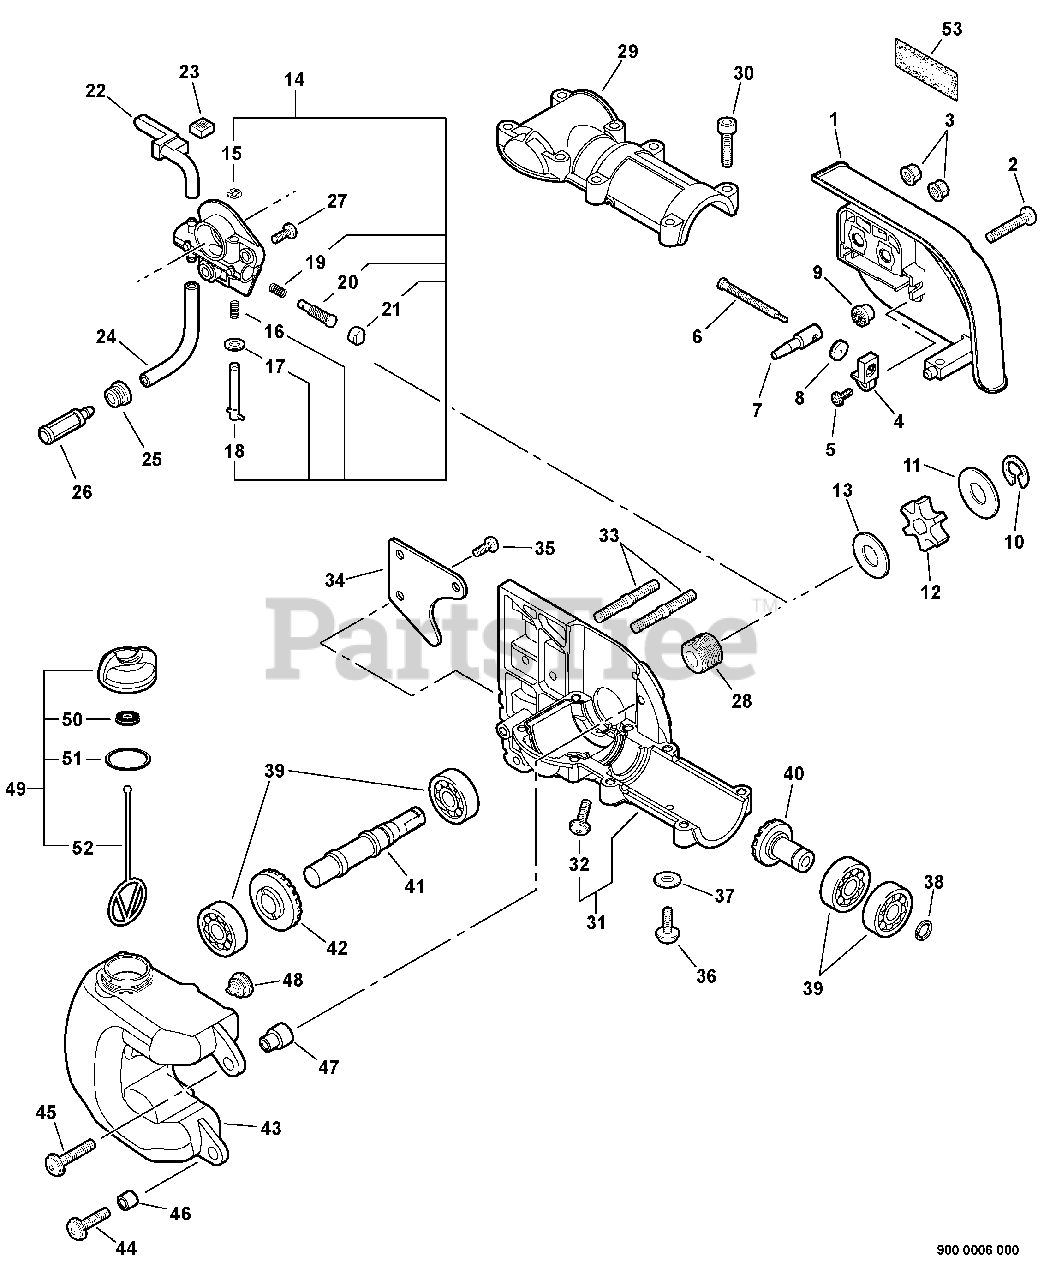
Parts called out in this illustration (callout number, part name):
1	GUARD, SPROCKET
2	SCREW - 5X20
3	NUT - 6 -- FLANGE
4	BRACKET, TENSIONER
5	SCREW - 4X8
6	SCREW, TENSIONER
7	TENSIONER, CHAIN
8	GEAR - BEVEL
9	GEAR - BEVEL
10	RING, RETAINING
11	WASHER - 10
12	SPROCKET, DRIVE
14	AUTO-OILER ASSY
15	RING, RETAINING
18	NEEDLE, ADJUST
20	PLUNGER
21	CAP, OIL PUMP
22	PIPE, OIL OUTLET
23	PAD, FOAM
24	PIPE - 3X6X75 -- BLACK
25	GROMMET
26	FILTER, OIL
27	SCREW - 5X10
28	GEAR - WORM
29	CASE, GEAR - UPPER
30	SCREW - 5X25
31	CASE, GEAR - LOWER
32	SCREW - 5X10
33	STUD, GUIDE BAR
35	SCREW - 5X10
36	SCREW - 5X10
37	WASHER - 5
38	RING, RETAINING - 12
39	BEARING, BALL - 6001
40	GEAR - BEVEL
41	GEAR - SHAFT
42	GEAR - BEVEL
43	TANK, OIL
44	SCREW - 5X20
45	SCREW - 5X25
49	CAP ASSY - ORANGE
50	WASHER - RUBBER
51	O-RING - 18
52	CONNECTOR, CAP
53	LABEL - ECHO
